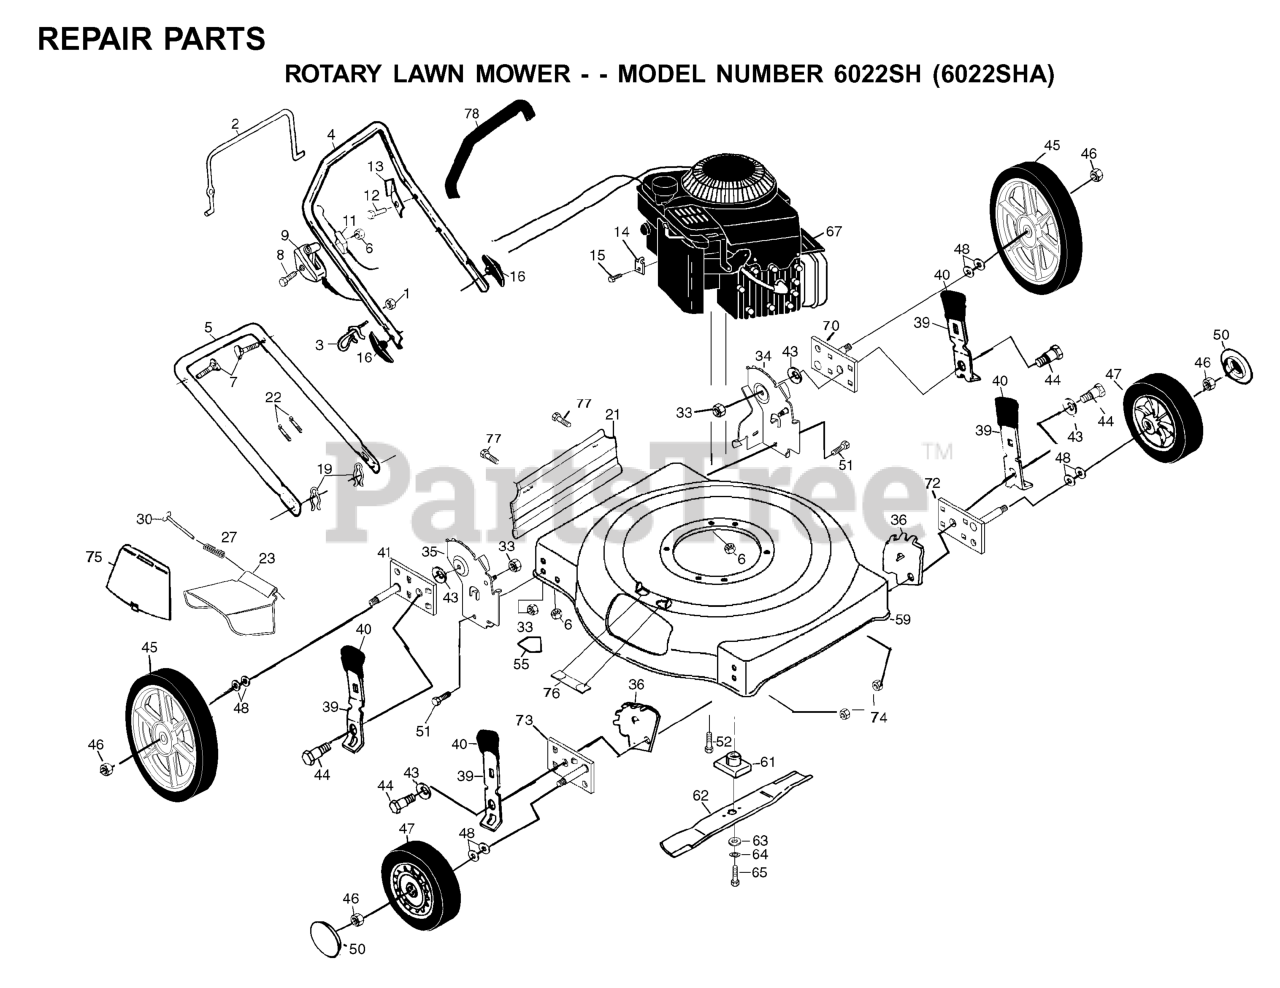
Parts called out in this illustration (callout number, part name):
1	NUT
3	ROPE GUIDE
5	HANDLE.LOWER.BLACK
6	NUT
7	HANDLE BOLT
8	SCREW 1/4-20 X 2.12
9	THROTTLE TRIGGER
11	ENGINE ZONE CONTROL
12	TAPPING SCREW
13	BRACKET UPSTOP
14	WASHER
15	SCREW.HEX.HEAD.WASHER.10-16
16	HANDLE KNOB
19	HAIRPIN COTTER
21	REAR DEFLECTOR, POULAN PR6N22
22	TIE GUIDE
27	TORSION SPRING
33	LOCKNUT
34	BRACKET, WHEEL SUPPORT(L)
35	BRKT ASM,HANDLE
36	WHEEL BRACKET ADJUSTER
39	REPL BY 532 1683-60
43	WASHER
44	SHOULDER BOLT
45	WHEEL.14X2.PR.SP.RAD.GY
46	HEX FLANGE LOCKNT
47	WHEEL.8X2.PR.LP.RAD.GREY
48	WAVE WASHER
50	CAP.HUB.BLACK.WALK
51	BOLT
52	BOLT 3/8-16X1-1/8
55	DECAL HYT
61	BLADE ADAPTOR
63	WASHER,HARDEN
64	LOCKWASHER
65	SCREW, HEX HD 3/8-24 X 1-3/8
72	AXLE ARM ASM (L)
73	AXLE ARM ASM
74	NUT.LOCK.5/16-18
75	MULCHER PLATE
77	BOLT.HEX.1/4.X.3/4.DICHROMATE
78	GRIP.HANDLE.FOAM
